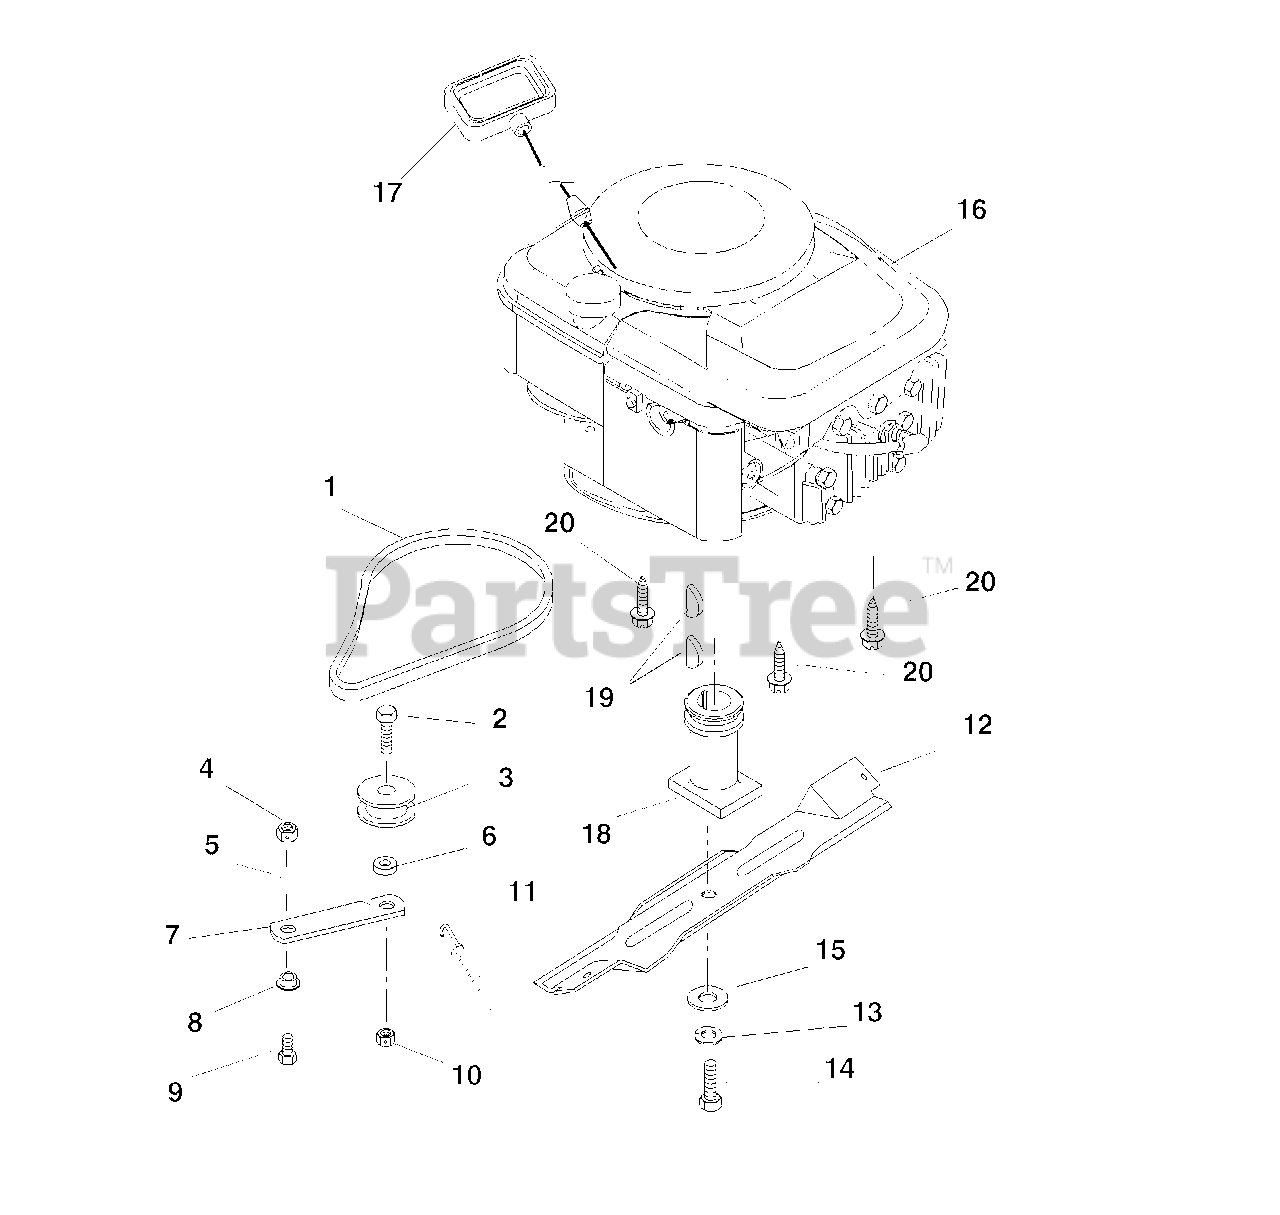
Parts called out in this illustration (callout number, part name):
1	V-BELT, 3L-COGGED
2	@BLT-HEX .44-14X1.50 GR5 YWZC
3	IDLER-FLAT 1.75 X .47
4	@NUT-LK-CTR .31-18 YWZC
5	@WSHR-FL-STL.344X.688X.065YWZC
6	BSHG-SLV .469 X .750 X .430
7	IDLER ARM
8	BSHG-FLG .325X.501X.250X1.120
9	@BLT-HEX .31-18X.75 GR5 YWZC
10	@NUT-LK-CTR .44-14 YWZC
11	SG-TENS .043X.44X3.31 WLD 5.8
12	BLADE LM 21 IN
13	@WSHR-LK .38X.094 REG YWZC
14	BLT-HEX .38-24 X 2.00 GR8 YWZC
15	WSHR-FL-STL .390X1.5X.125 YWZC
16	ENGINE, B&S QUANTUM 6.5HP
17	HANDLE, RECOIL START
18	ADAPTER, BLADE
19	KEY-WDRF .156X.625X.25 SAE 6
20	@SCR-TAP .38-16X1.00 HWH TR YZ
